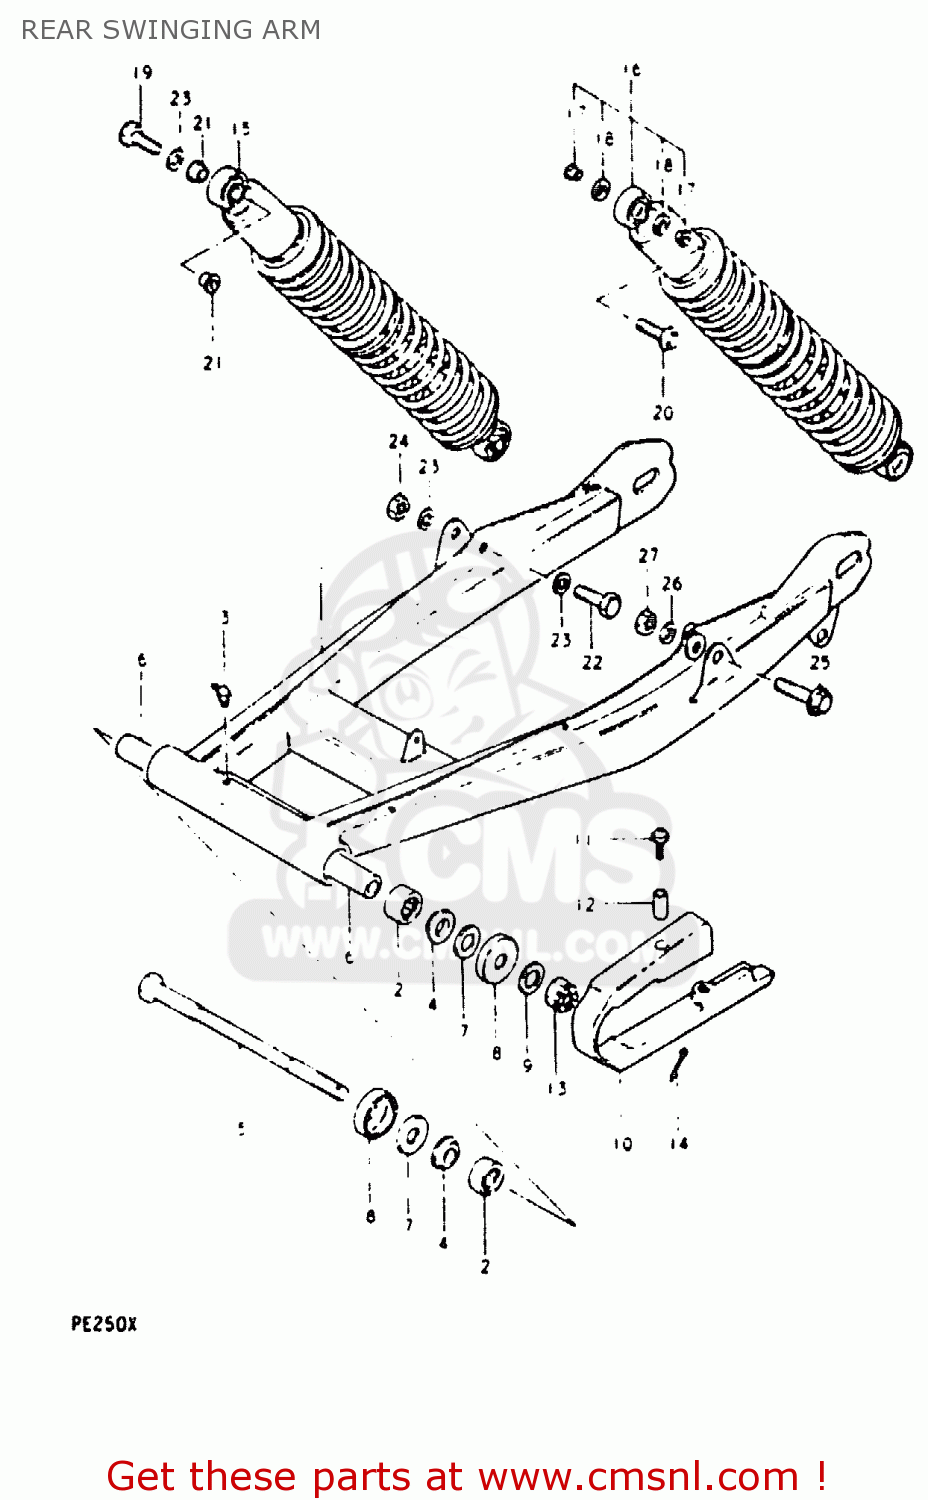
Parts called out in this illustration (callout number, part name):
1	SWING ARM ASSEMBLY,REAR
2	BEARING
3	NIPPLE,GREASE
4	BUSHING,REAR SWING ARM PIVOT
5	SHAFT,REAR SWING ARM
6	SPACER,REAR SWING ARM
7	WASHER
8	COVER,RR SWGARM DUST SEAL
9	WASHER
10	BUFFER,CHAIN TOUCH DEFLECTOR
11	SCREW,CHAIN TOUCH DEFEND
12	SPACER (5.5X8X4)
13	NUT 14MM
14	COTTER PIN
15	ABSORBER ASSEMBLY,REAR SHOCK
16	ABSORBER ASSEMBLY,REAR SHOCK
17	SPACER,REAR SHOCK ABSORBER
18	DUST SEAL,REAR SHOCK
19	BOLT
20	BOLT 10X40
21	SPACER,RR SHK ABS INNER
22	BOLT(8X46)
23	WASHER
24	NUT
25	BOLT(10X52)
26	WASHER
27	NUT
